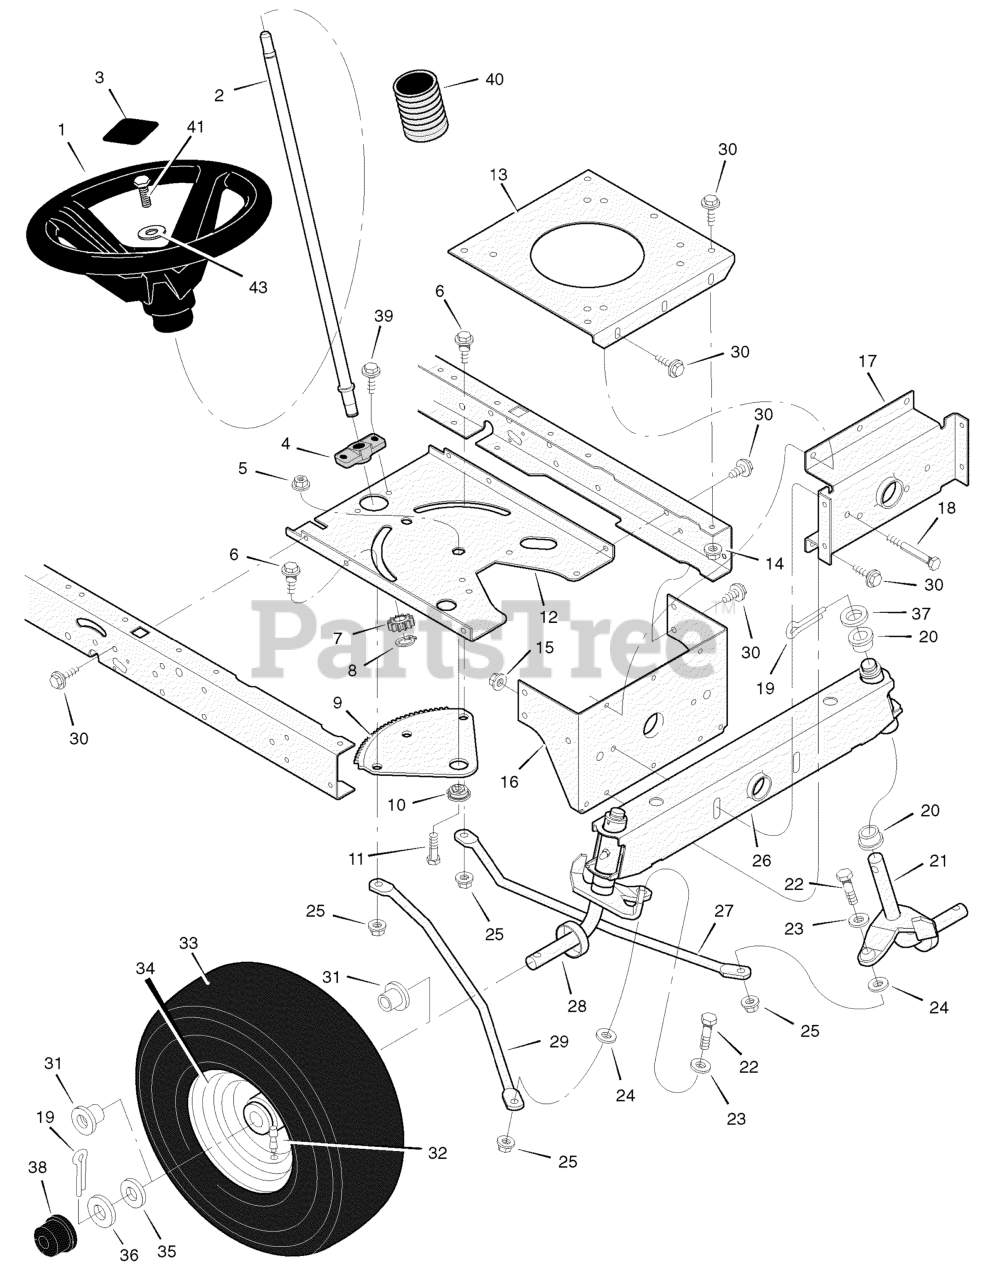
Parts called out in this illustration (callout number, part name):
1	Wheel, Steering
2	Post, Steering
3	Cap, Steering Wheel
4	Bearing
5	Nut, Flange
6	Bolt, Shoulder
7	Gear, Pinion
8	Ring, Snap
9	Gear, Sector
10	Bearing
12	Plate, Steering
13	Plate, Engine
14	Nut, Flange
15	Nut, Flange
16	Bracket, Hanger
17	Axle, Hanger
18	Bolt
19	Pin, Cotter
20	Bearing
21	Spindle Assembly, Left
22	Bolt
23	Washer
24	Washer
25	Nut, Flange
26	Axle Assembly
27	Drag Link, Left
28	Spindle Assembly, Right
29	Drag Link, Right
30	Screw
31	Bearing, Wheel
32	Stem, Valve
33	Tire *
34	Wheel and Tire Assembly
35	Washer
36	Washer
37	Washer
38	Hub Cap
39	Screw
40	Cover
41	Screw, Hex
43	Washer
